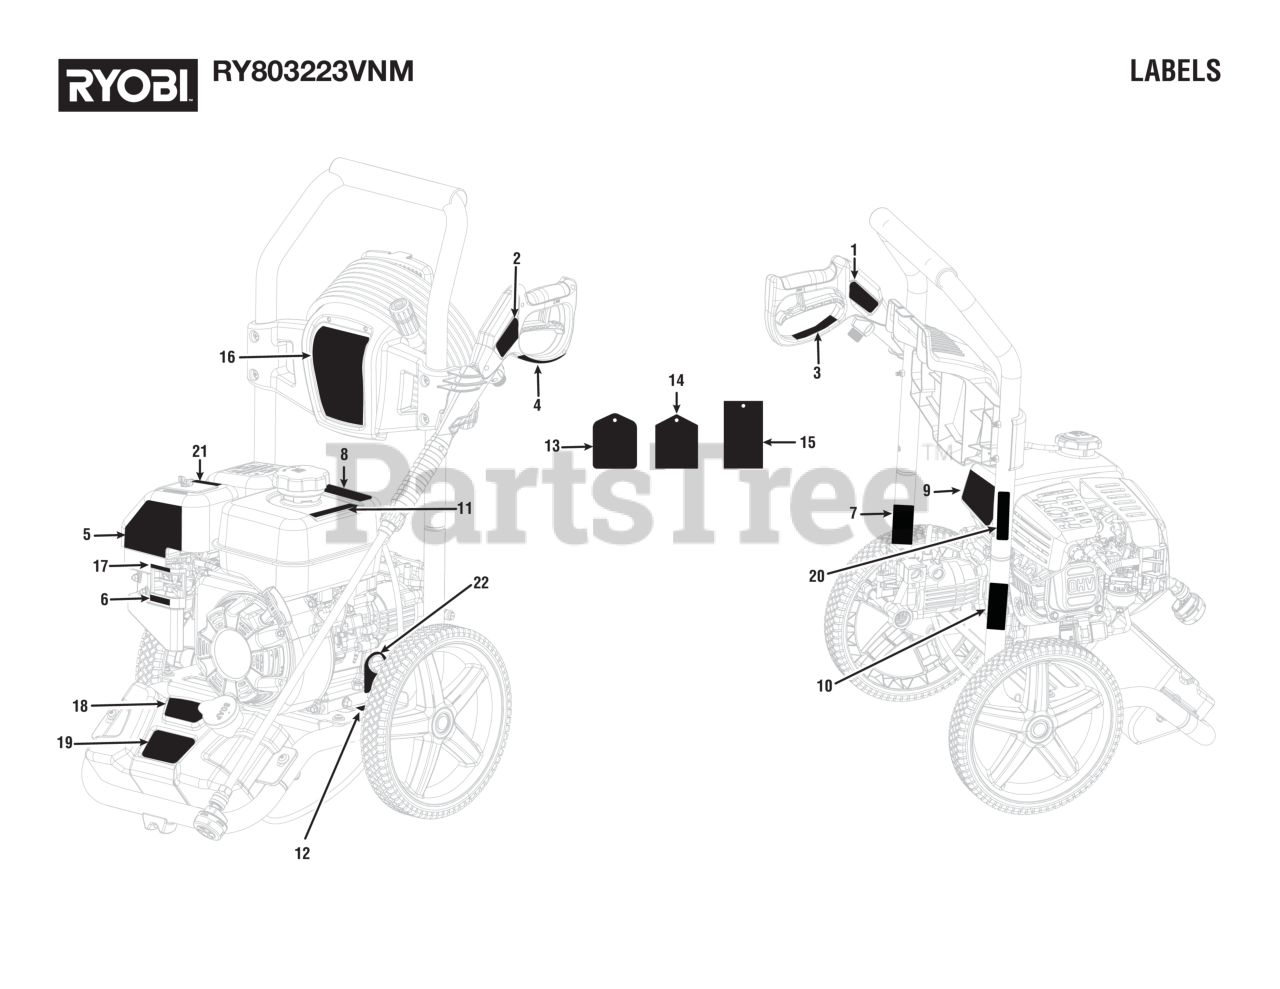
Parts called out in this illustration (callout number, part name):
1	LABEL, TRIGGER HANDLE LOGO
2	Trigger Handle Warning Label (English)
3	Label (Trigger Handle Warning, French & Spanish)
4	Rating Label
5	Engine Brand Label
6	Fuel Valve Label
7	Warning Label
8	Hot Surface and Exhaust Label
9	Danger Label
10	UL Fire Warning Label Spark Arrestor)
11	No E85 Label
12	Oil Fill Location Label
13	Quick Start Hangtag
14	5- In- 1 Nozzle Hangtag
15	Danger Hangtag
16	Performance Label
17	Choke Label
18	Soap Tank Label
19	Soap Tank Logo Label
20	Inquires Label (Ryobi)
21	EMC ICES-2/NMB-2 Label (Canada)
22	Label (Oil Dipstick Hangtag)
